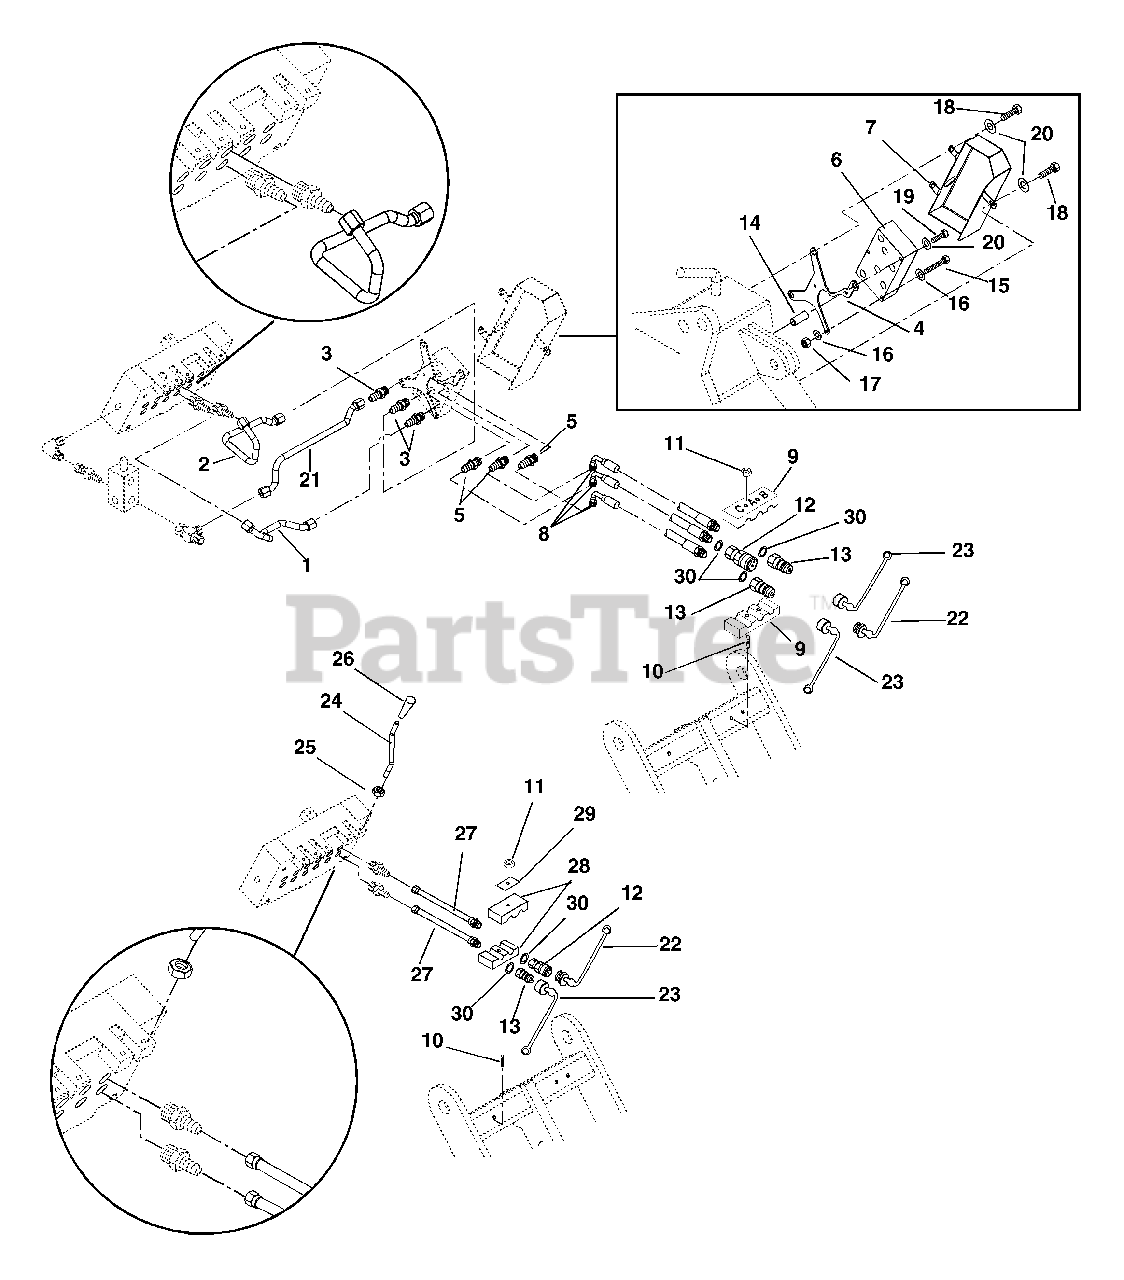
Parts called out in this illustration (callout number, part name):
1	Tube-Valve Bank Auxiliary To Trencher Valve
2	Tube-Valve Bank Auxiliary To Trencher Valve
3	Adapter-Straight .750-16 x .875-14
4	Bracket-Trencher Valve
5	Adapter-Straight .750-16 x .750-16
6	Valve-Trencher Control
7	Guard-Heat
8	Hose-Hydraulic Trencher Valve
9	Clamp-Hydraulic .500 I.D. 3 Hose
10	Stud-8M-1.25 x 3.62
11	Nut-Locking-Nylon M8-1.25
12	Coupling-Female Quick .500-14
13	Coupling-Male Quick.500-14
14	Spacer .344 x .750 x 1.500
15	Bolt-Hex M6-1x65
16	Washer-Flat-Steel .281 x .62 x .065
17	Nut-Locking-Nylon M6-1
18	Bolt-Hex M8-1.25 x 20
19	Bolt-Hex M8-1.25 x 65
20	Washer-Flat-Steel .344 x .688 x .065
21	Tube-Trencher Valve Return Line
22	Plug-Dust
23	Cap-Dust
24	Lever-4N1 Bucket Control
25	Nut-Jam M10-1.5
26	Knob-Control Lever
27	Hose-Hydraulic 4N1 Bucket
28	Clamp-Dual Hose .500 I.D. Hose
29	Plate-Cover
30	Seal, Bonded
